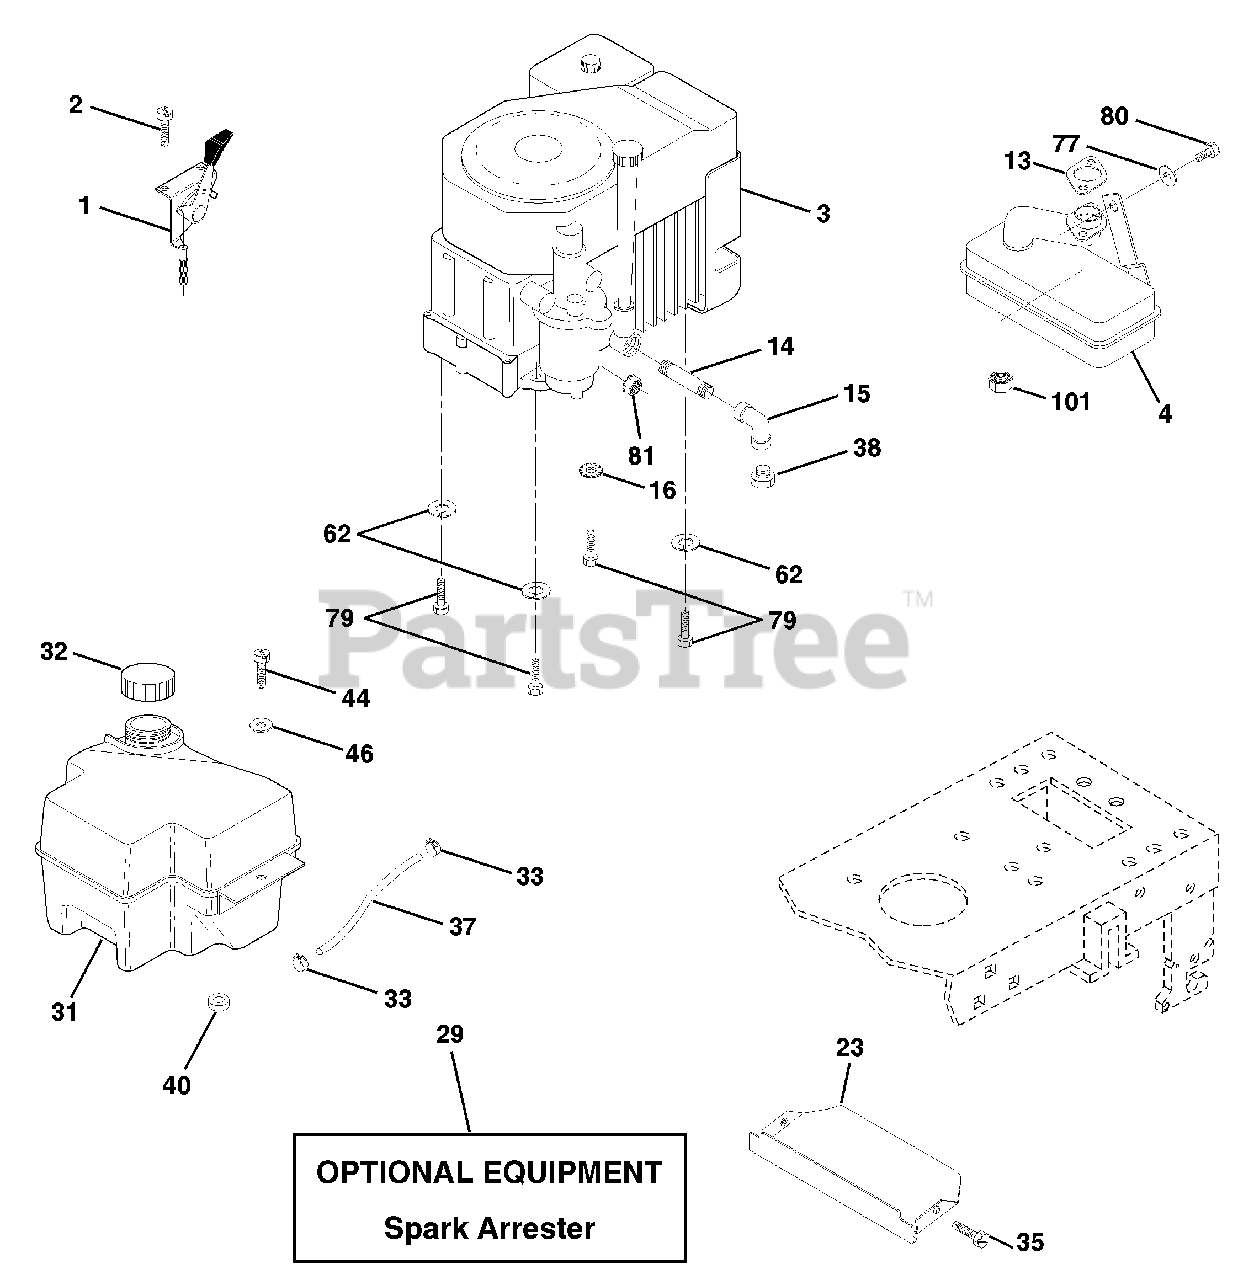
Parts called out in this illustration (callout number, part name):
1	Control THTICH 27 LH FLAG DOM
2	Screw Hex Thd Cut 1/4-20 x 5/8 T
4	Muffler
13	Gasket Kohler CV13-CV16.5
14	Nipple Pipe 3/8 Npt X 3-1/2
15	Elbow Std 90 Degree 3/8-18 Npt
16	Washer Lock Ext Tooth 5/16
23	Shield Browning/Debris Guard
29	Kit Spark Arrestor (Flat Scrn)
31	Tank Fuel Front 2 00 Gal Nat
32	Cap Asm Fuel W/sym Vented
33	Clamp Hose Black
35	Screw
37	Line Fuel 20"
38	Plug Oil Drain
40	Bushing Snap Nyl Blk Fuel Line
44	Screw Hexwsh Thdrol 1/4-20x3/4
46	Washer 9/32 X 7/8 X 16 Ga
62	Washer Lock Hvy Hlcl Spr 5/16
77	Washer 5/16 x 3/4 x 16 Ga.
79	Bolt Hex
80	Bolt Hex Hd 5/16-18 UNC x 1/2
81	Nut Flange 1/4-20 Starter Nut
101	Nut Flange Me-1.25 Non-LK
